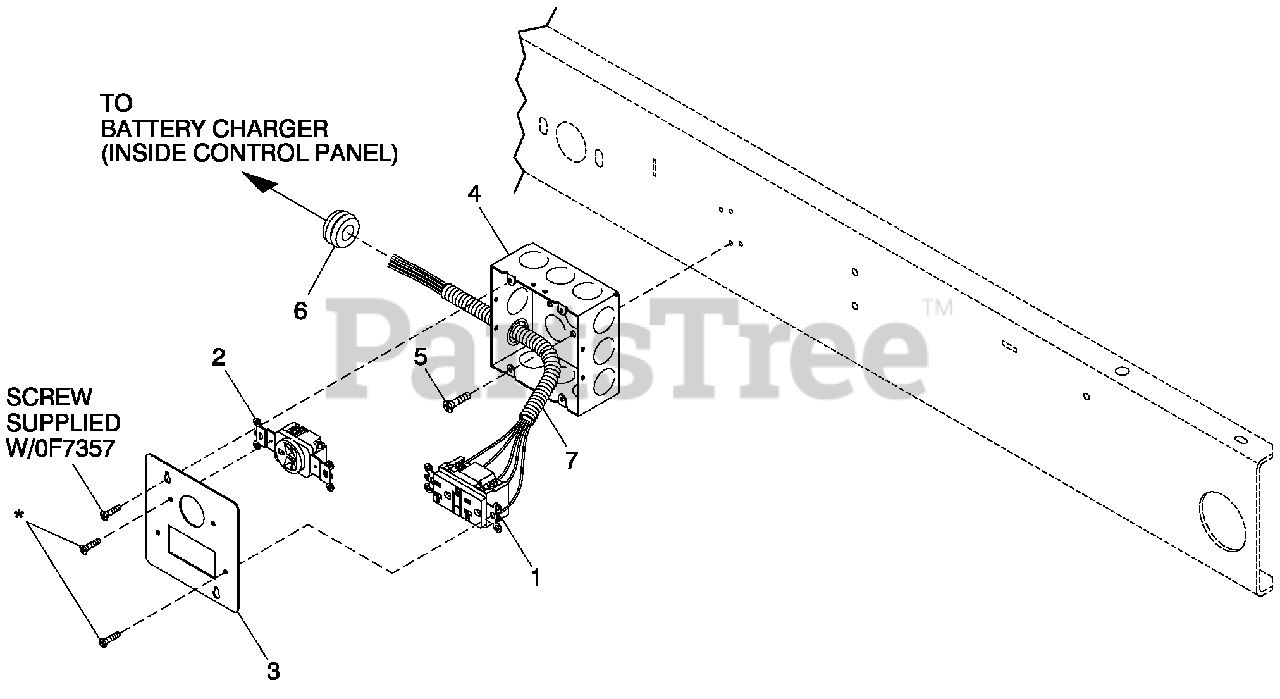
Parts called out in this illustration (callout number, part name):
1	OUTLET 20A GFCI
2	OUTLET 15A 250V NEMA 6-15R IVY
3	BOX SQUARE 4-11/16 W/KNO'S
4	SCREW HHTT #10-24 X 3/8 CZ
5	COVER DUAL RECEPT 120/240
6	GROMMET .87 X .25 X .62
7	HARN ALT CON BOX 1PH QT
